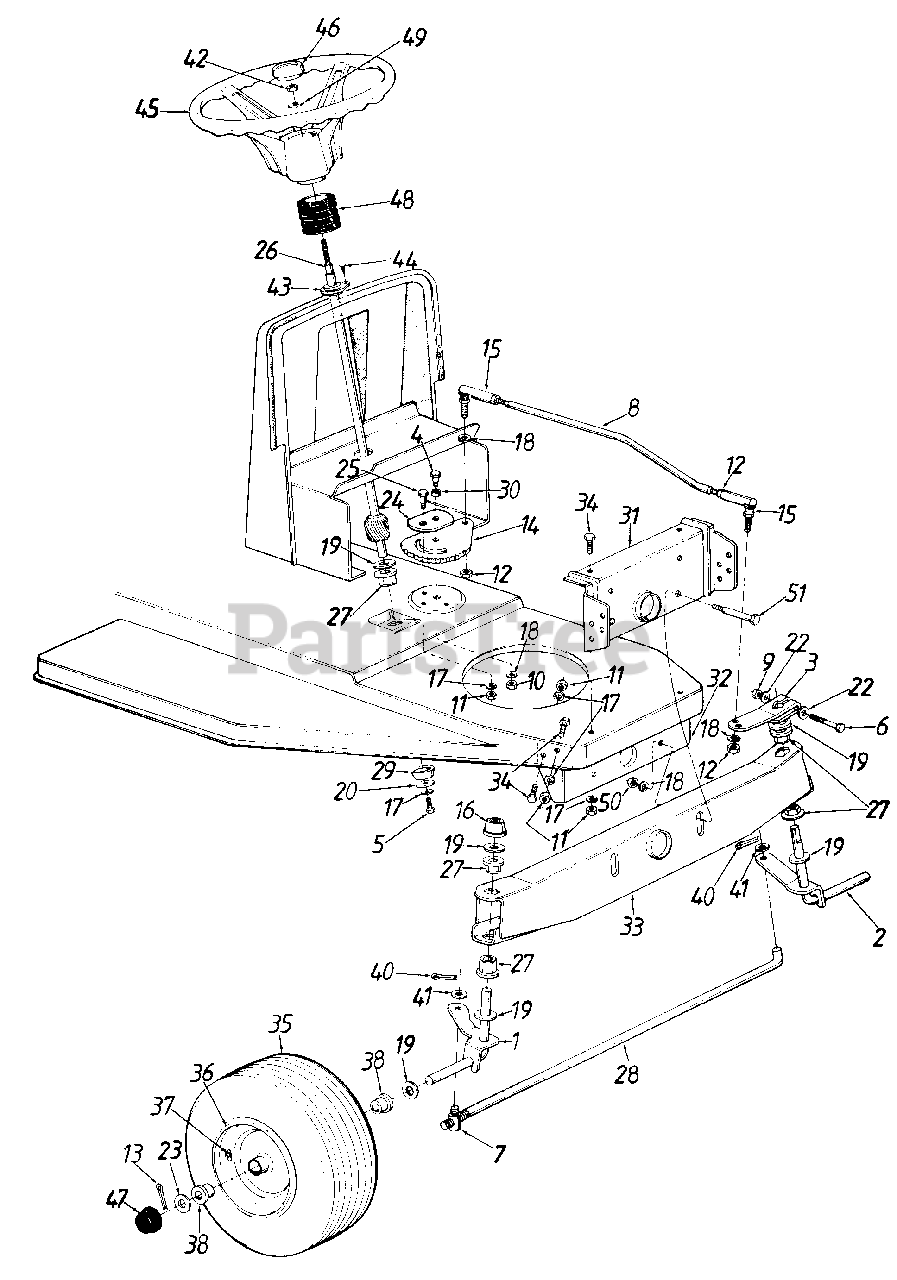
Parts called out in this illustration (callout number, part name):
1	Front Axle Ass'y.-R.H.
2	Front Axle Ass'y.-L.H.
3	Steering Arm
4	Hex Bolt 3/8-24 x 1 " Lg.
5	Hex Bolt 5/16-18 x .62"
6	Hex Bolt 5/16-24 x 2" Lg.*
7	Ferrule
8	Steering Drag Link
9	Hex L-Nut 5/16-24 Thd.
10	Hex Nut 3/8-24 Thd.
11	Hex Nut 5/16-18 Thd.
12	Hex Jam Nut, 3/8-24
13	Cotter Pin 1/8 Dia.
14	Steering Gear Segment
15	Drag Link Ball Joint 3/8-24 Thd.
17	L-Wash. 5/16" I.D.
18	L-Wash. 3/8" I.D.*
19	Fl-Wash. .64" I.D. x 1.24"
20	Fl-Wash. .340" I.D. x 1.125"
22	Spr. Wash. .32 I.D. x .62
23	Fl-Wash. .635 I.D. x 1.585
24	Retainer Plate
25	Shld. Bolt .437 Dia. x .350
26	Steering Shaft
27	Hex Flange Brg. .634 Dia.
28	Tie Rod 18.37 Lg.
29	Spacer .985 I.D.
30	Spacer .380 I.D.
31	Front Pivot Bar Support Brkt.
32	Rear Pivot Bar Support Brkt.
33	Pivot Bar Ass'y.
34	Hex Bolt 5/16-18 x .75" Lg.*
35	Front Wheel Ass'y. Comp. 13 x 6
37	Air Valve
38	Flange Bearing .632 I.D.
40	Cotter Pin 3/32" Dia.
41	Fl-Wash. .406" I.D. x .75"
42	Hex L-Nut 5/16-24 Thd.
43	Steering Column Brg.
44	Cr-Sunk Scr. #10 x 5/8" Lg.
45	Steering Wheel
46	Steering Wheel Cap
47	Hub Cap
48	Bellow Steering Column
49	Bell-Wash. .345 I.D. x .88
50	Hex Nut 3/8-16 Thd.*
51	Shld. Bolt 1/2" Dia. x 2.32"
